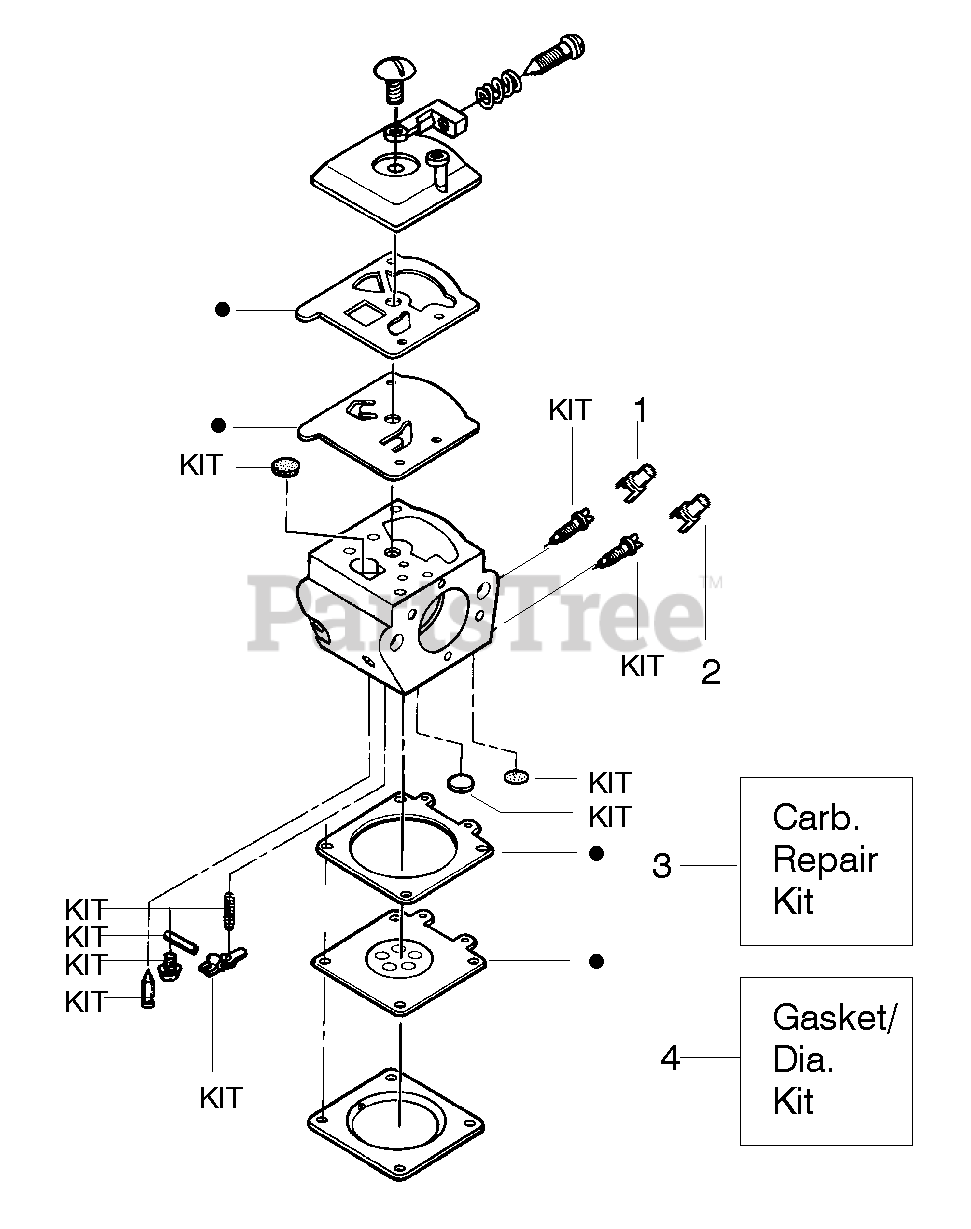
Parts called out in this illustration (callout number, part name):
1	Limiter Cap-High (brown)
2	Limiter Cap-Low (tan)
3	Carburetor Repair Kit (KIT= Indicates Contents) Zama (GND-27)
4	Gasket Diaphragm Kit Zama (KSO31173)
